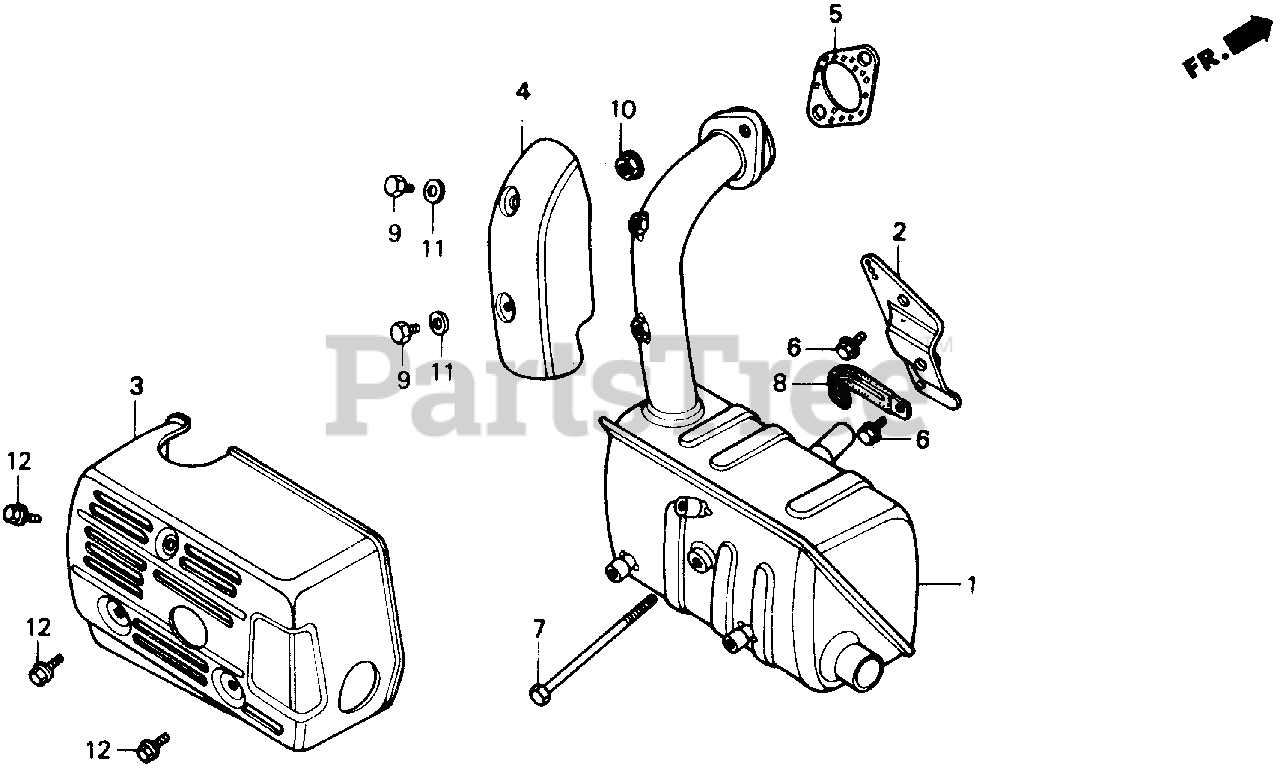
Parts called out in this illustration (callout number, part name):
1	MUFFLER (NOT AVAILABLE)
2	STAY, MUFFLER (NOT AVAILABLE)
3	PROTECTOR, MUFFLER
4	PROTECTOR, EX. PIPE
5	GASKET, MUFFLER
6	BOLT, FLANGE (6X12) (CT200)
7	BOLT, HEX. (8X113)
8	CLIP, CABLE
9	BOLT, HEX. (6X6) (NOT AVAILABLE)
10	NUT, FLANGE (8MM)
11	WASHER, PLAIN (6MM)
12	BOLT, FLANGE (6X10)
